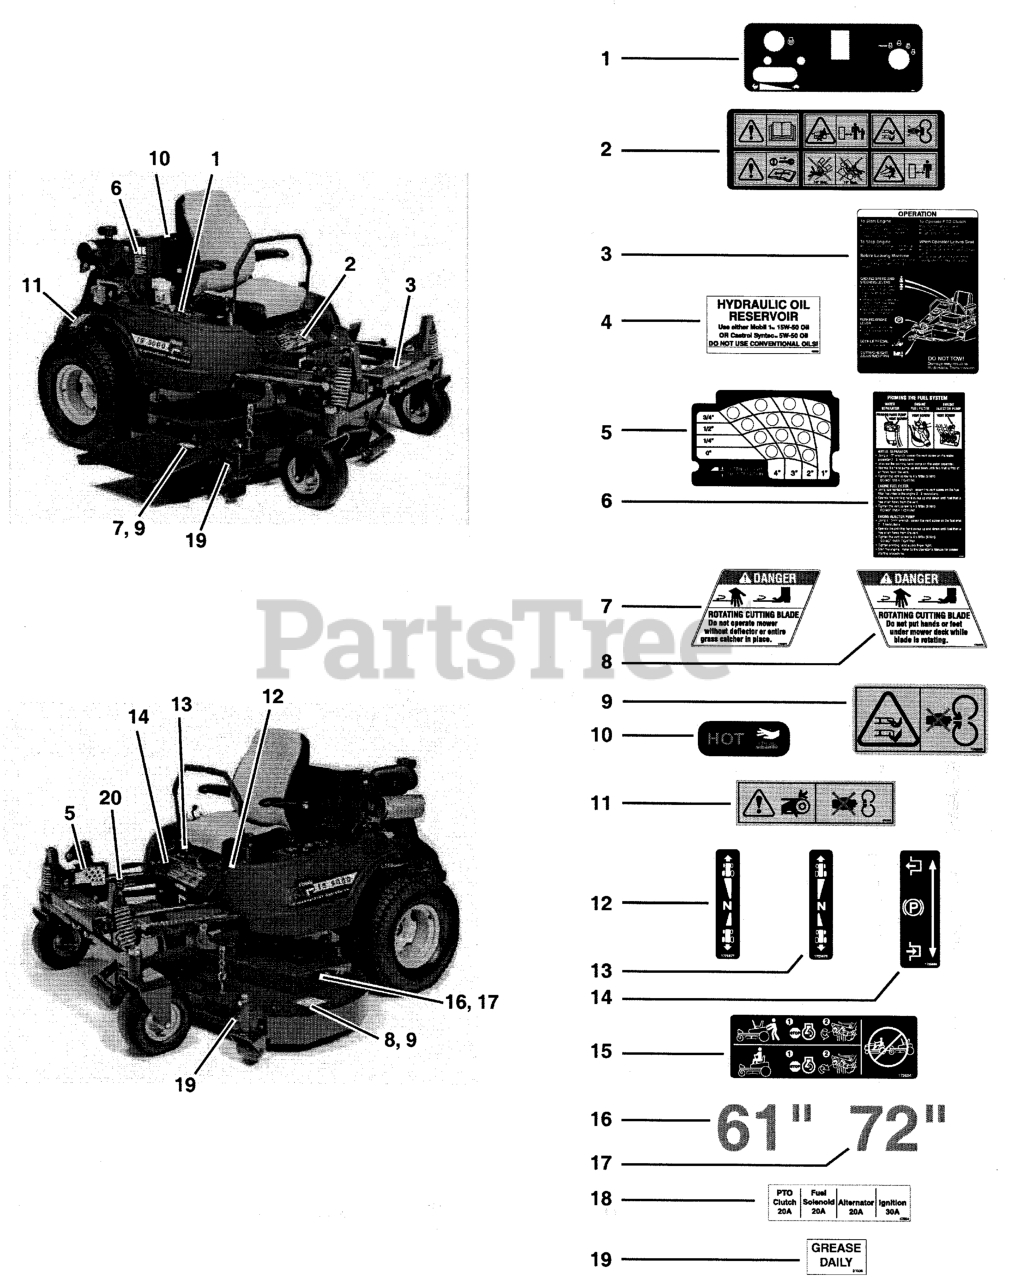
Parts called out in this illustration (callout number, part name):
1	DECAL, Control Panel
2	DECAL, Warning, Main
3	DECAL, Operation
4	DECAL, Oil Reservoir
5	DECAL, Deck Height
6	DECAL, Priming Instructions
7	DECAL, Danger (Chute In Place)
8	DECAL, Danger (Hand Under Deck)
9	DECAL, Warning, Mower
10	DECAL, Hot Surface
11	DECAL, Warning, Hand In Belt
12	DECAL, Ground Speed, LH
13	DECAL, Ground Speed, RH
14	DECAL, Parking Brake
15	DECAL, CZT Hydro Release
16	DECAL, 61"
17	DECAL, 72"
18	DECAL, Fuse Location
19	DECAL, Grease Daily
20	Model/Serial Number Tag
21	DECAL, 105dB (Export models only)
